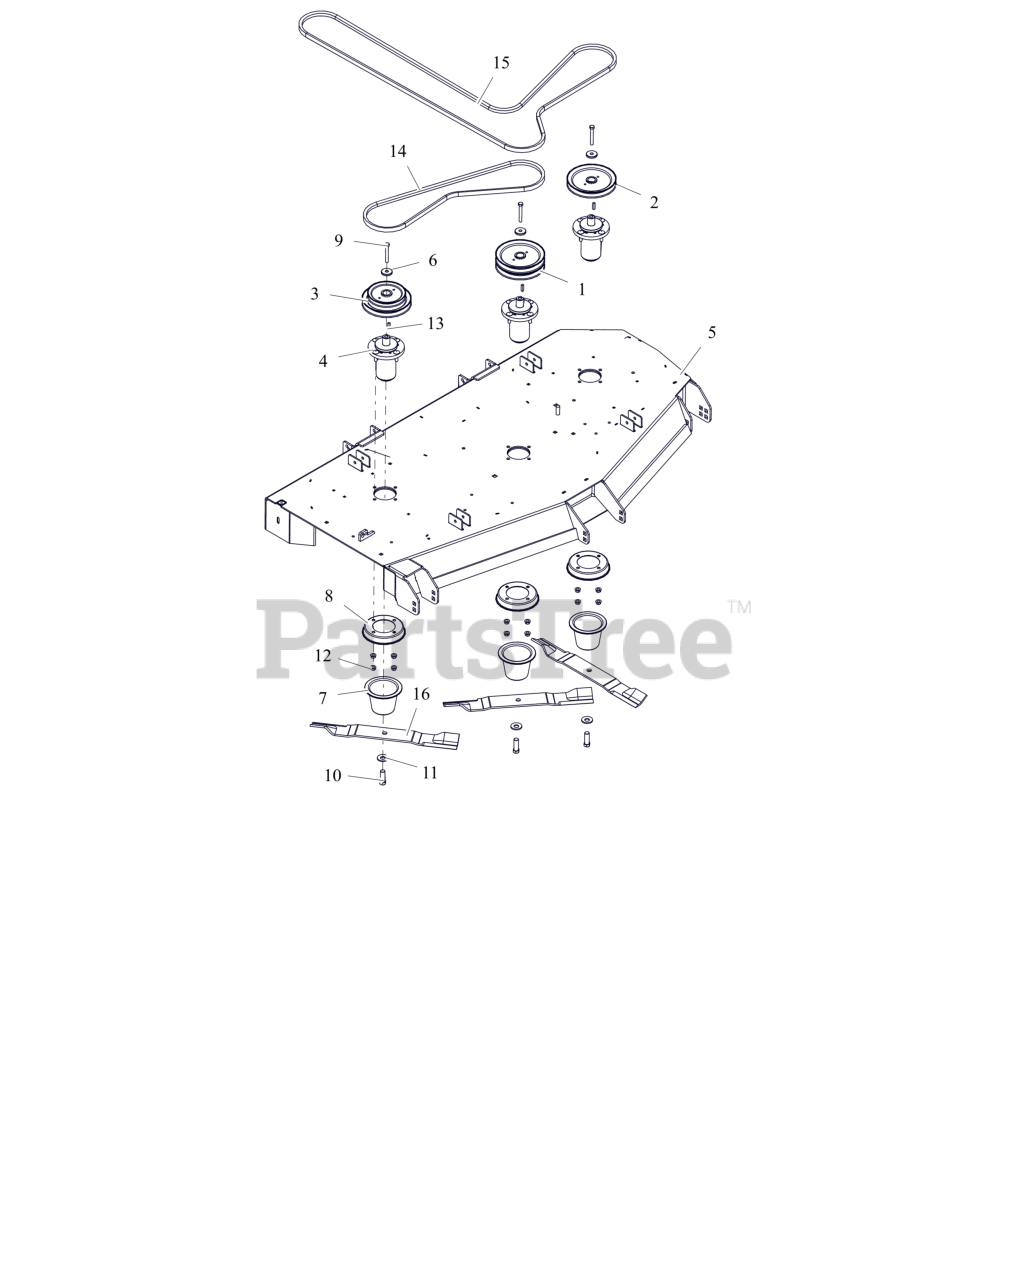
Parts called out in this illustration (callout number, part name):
1	PULLEY, DOUBLE 1.000 ID X 6.750 OD
2	PULLEY, V-1" ID X 6.75 OD
3	PULLEY, DBL-1"IDX6.75"&5.25"OD
4	ASM, MAINT FREE ALUM SPINDLE
5	WLDMT, 60" SIDE DISCH DECK (RED) W/ SAFETY DECALS
6	RETAINER, SHEAVE
7	GUARD, SPINDLE LOWER
8	GUARD, SPINDLE TOP
9	BLT, HEX .38-16X2.75 G8 ZCC
10	BLT, HEX .62-18X1.75 G8 ZCC
11	WSHR-BLVL .669X1.535X.138
12	NUT-LK-CTR-FLG .375-16 GF ZCC
13	KEY, SQ .25X.25X1.00 RC 40-50
14	V-BELT, B-COGGED
15	BELT, B-SECTION EPDM RAW EDGE
16	BLADE, MOWER (20.50")
